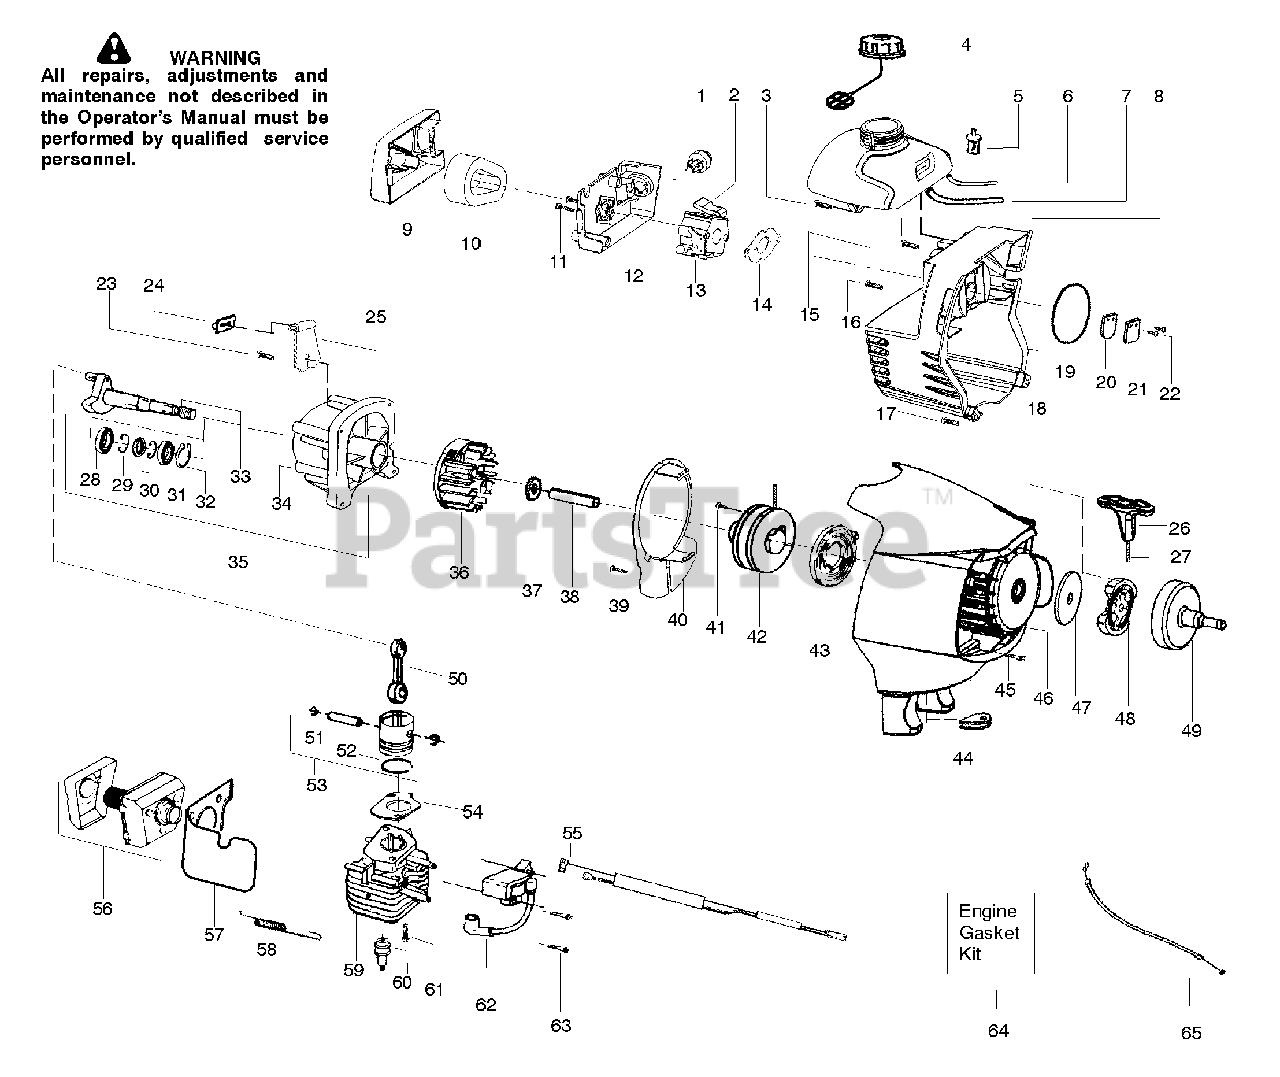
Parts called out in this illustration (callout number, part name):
1	Bulb-Purge
2	Kit-Choke Lever
3	Screw-tank
4	Cap-Fuel w/ret.
5	Assy-Fuel pickup
6	Kit-Fuel line
7	Kit-Fuel/Purge line
9	Cover-Air box
10	Filter-Air
11	Screw-Carb.
13	Assy-Carb
14	Gasket-Carb.
15	Assy-Fuel Tank
16	Screw-Crankcase
17	Screw-Shroud
19	O-ring-Shroud
20	Valve-Reed
21	Stop-Reed
22	Screw-Reed stop
23	Screw-Retainer
24	Isolator-Tank
25	Ret.-Tank
26	Handle-Starter
27	Kit-Rope
28	Bearing-Inner
29	Retainer
31	Bearing-Outer
32	Ret.-Crankshaft
33	Assy-Crankshaft
34	Assy-Crankcase
35	Assy-C'case/C'shaft
36	Assy-Flywheel
39	Screw-Baffle
40	Plate-Baffle
41	Screw-Rope
42	Kit-Pulley
43	Spring-Starter
45	Screw-F/hsg.
46	Assy.-Fan Housing
47	Washer-Clutch
48	Assy-Clutch
49	Drum-Clutch
50	Assy-Conn. Rod
51	Ret.-Piston pin
52	Ring-Piston
53	Kit-Piston
54	Gasket-Cylinder
55	Assy-Leadwire
56	Kit-Muffler
58	Spring-Muffler
59	Kit-Cylinder
60	Plug-Spark
61	Bolt-Cyl. 1/4-20'
62	Module-Ignition
63	Screw-Module
64	Kit-Gasket
65	Assy-Throttle cable
